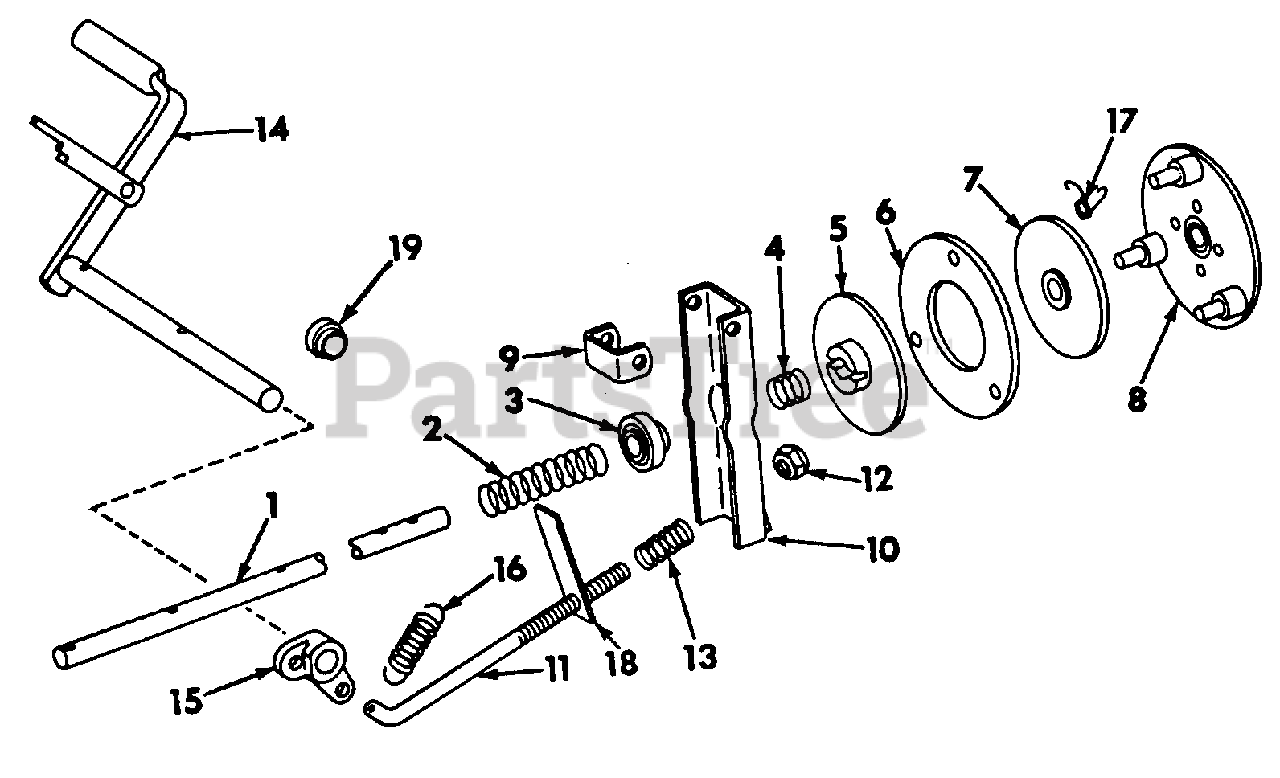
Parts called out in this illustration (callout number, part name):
1	Package, Clutch Shaft Service
2	Spring, Clutch Loading
3	Bearing, Clutch Throwout Ball
4	Spring, Clutch Teasing
5	Hub Assy, Pressure Plate
6	Disc, Clutch Driving
7	Hub Assy, Pressure Plate Locating
8	Plate Assy, Driving
9	Bracket, Clutch Operating Yoke
10	Lever, Clutch Release
11	Rod, Release
12	Nut, 3/8-24 Hex Self-Align
13	Spring, Clutch Release Rod
14	Pedal Assy, Clutch & Brake
15	Arm, Clutch & Brake Pedal
16	Spring, Pedal Return
17	Spring, Clutch Driving Disc
18	Strip, Safety Switch Release Lever
19	Bearing, Clutch Pedal Shaft
